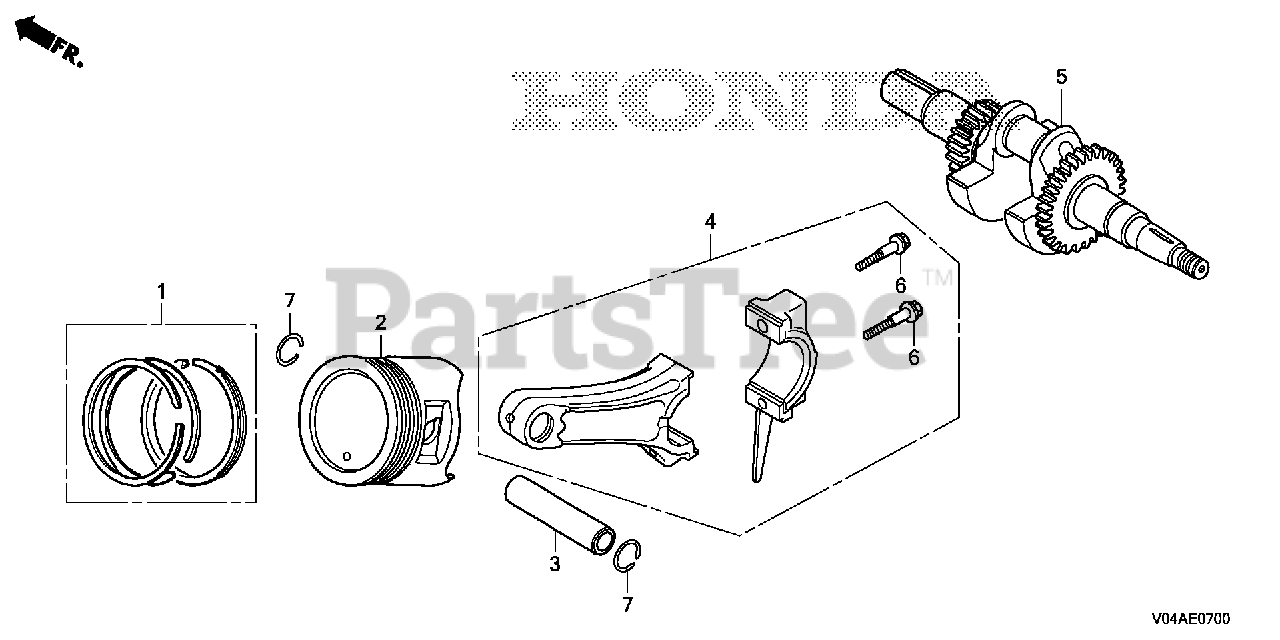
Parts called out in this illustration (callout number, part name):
1	RING SET, PISTON (STD) (TPR)
1	RING SET, PISTON (STD) (RIKEN)
1	RING SET, PISTON (0.25) (TPR)
1	RING SET, PISTON (0.25) (RIKEN)
1	RING SET, PISTON (0.50) (TPR)
1	RING SET, PISTON (0.50) (RIKEN)
1	RING SET, PISTON (0.75) (TPR)
1	RING SET, PISTON (0.75) (RIKEN)
2	PISTON (STD)
2	PISTON (0.25)
2	PISTON (0.50)
2	PISTON (0.75)
3	PIN, PISTON
4	ROD ASSY., CONNECTING (UNDER SIZE) (NOT AVAILABLE)
4	ROD ASSY., CONNECTING (TH)
5	CRANKSHAFT
6	BOLT, CONNECTING ROD
7	CLIP, PISTON PIN (18MM)
